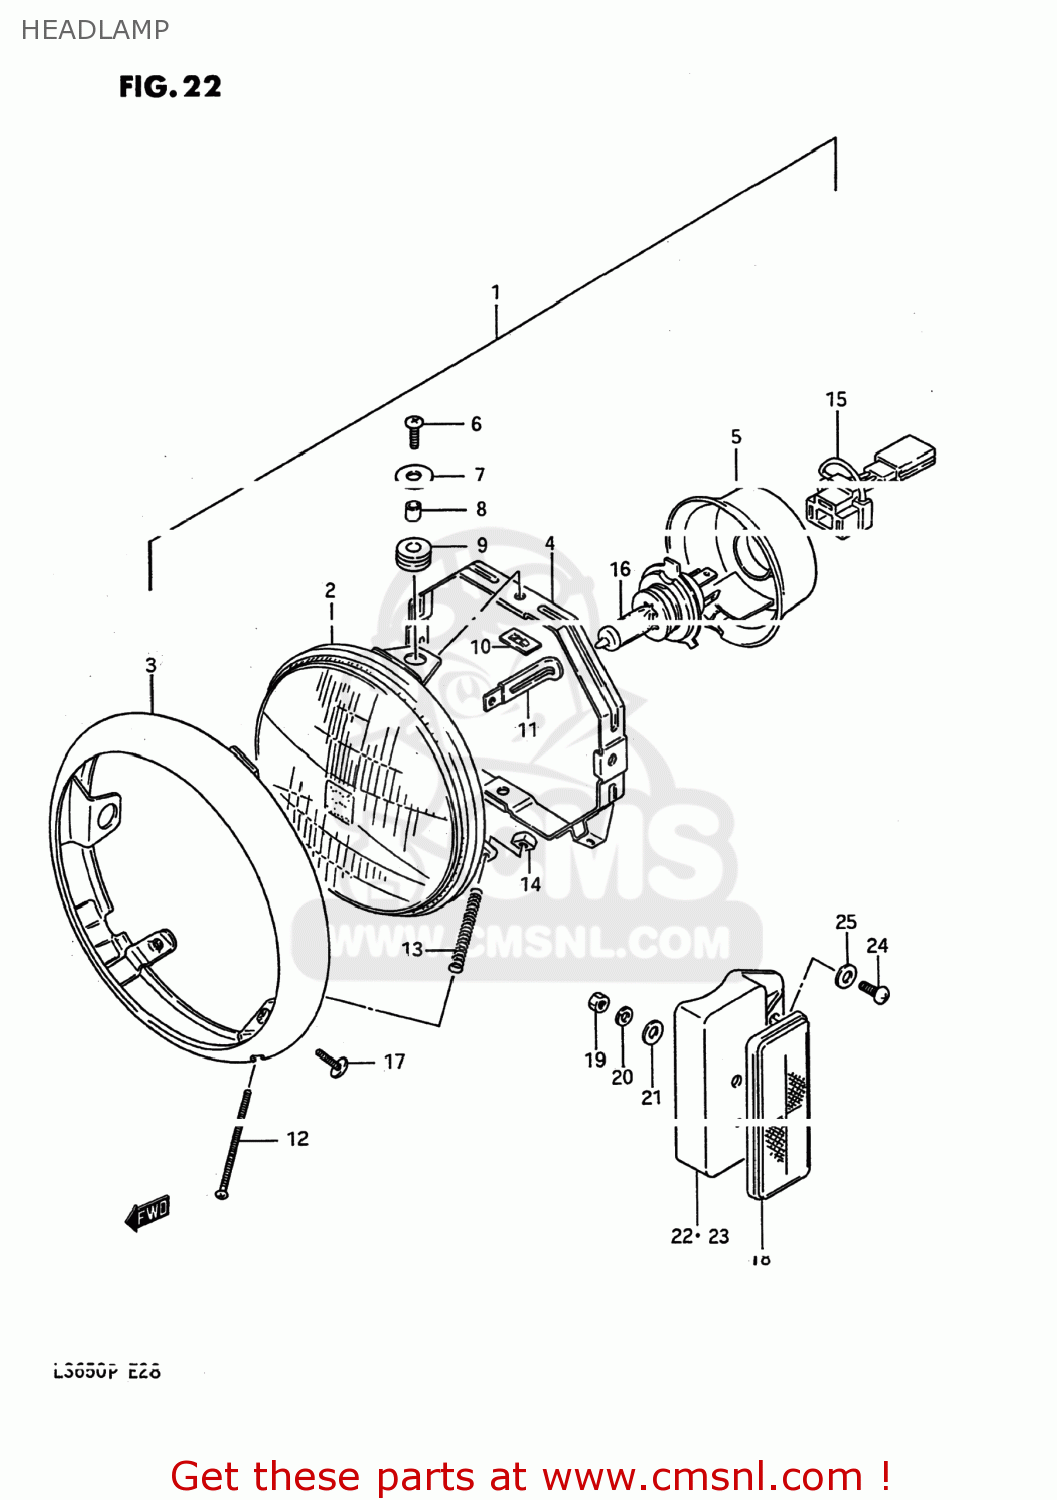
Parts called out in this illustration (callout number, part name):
1	HEADLAMP ASSY
2	UNIT,LAMP
3	RIM
4	RING,MOUNTING
5	COVER,SOCKET
6	SCREW(5X14)
7	WASHER
8	SPACER
9	CUSHION
10	NUT
11	CLAMP
12	SCREW,HEADLAMP ADJUST
13	SPRING,HEADLAMP ADJUST
14	NUT
15	SOCKET
16	BULB(12V60/55W,H4)
17	SCREW
18	REFLEX REFLECTOR,FR SIDE
19	NUT
20	LOCK WASHER
21	WASHER(5.2X16X1)
22	BRACKET,FR SIDE RR,R
23	BRACKET,FR SIDE RR,L
24	SCREW, FRONT & REAR
25	WASHER(5.2X16X1)
